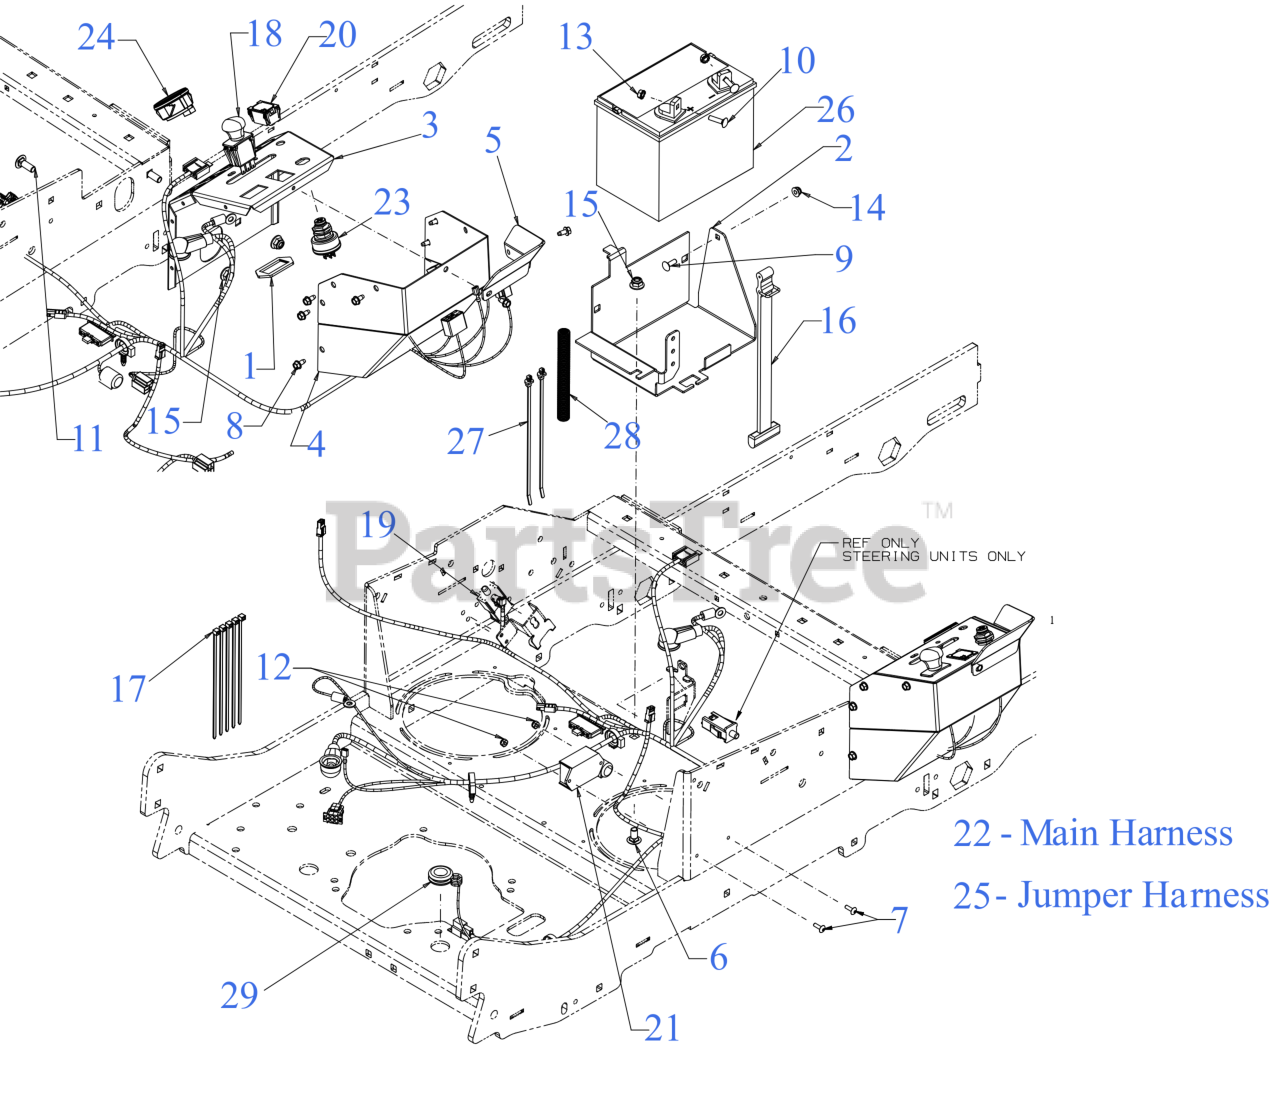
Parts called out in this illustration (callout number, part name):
1	BRACKET-PTO SWITCH
2	BATTERY MOUNTING BRACKET
3	CONTROL POD - RH
6	CARRIAGE BOLT 3/8-16 x .750 GR5
7	SCREW #10-24 x .62
8	SCREW 1/4-20 X.500
9	SCREW 1/4-20 x .75 GR5
10	SCREW 1/4-20 x 1 GR5
11	CARRIAGE BOLT 3/8-16 x 1.00 GR5
13	SEMS NUT 1/4-20
14	FLANGE LOCK NUT
16	BATTERY RETAINER STRAP
17	7" CABLE TIE
18	PTO SWITCH (BLACK KNOB) TEXT SYM
19	3 POLE SWITCH ( NC-NO-NO)
21	CONTROL PANEL (SOFT CLUTCH)
22	WIRE HARNESS ASSEMBLY KOH/KAW EFI
23	KEY SWITCH (3 POSITION)
24	DUAL FUEL GAUGE
25	JUMPER HARNESS (W/RELAY)
26	BATTERY (230 CCA AGM U1-280)
26	BATTERY
26	Purchase Battery Locally
27	CABLE TIE
28	CONVOLUTED CONDUIT 1"
29	RUBBER GROMMET
